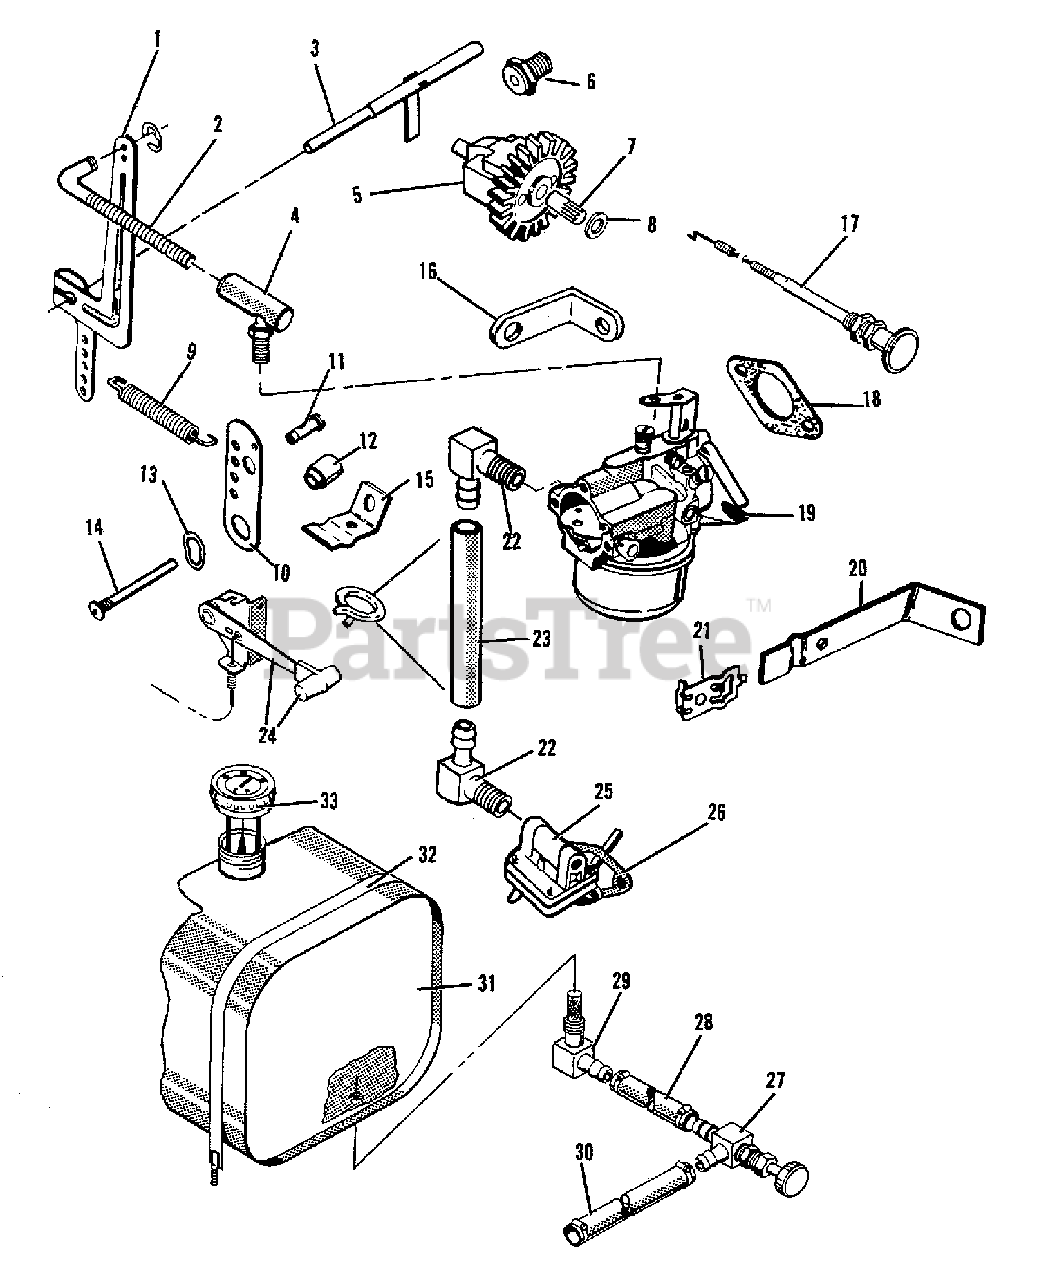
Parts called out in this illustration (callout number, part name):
1	LEVER, Governor
1	SCREW, 1/4 NC x 1-1/4
1	NUT, 1/4 NC
2	ROD, Throttle
2	RETAINER, Rod
3	SHAFT ASSEMBLY, Governor Cross
4	JOINT ASSEMBLY, Ball
4	LOCKWASHER, #10
4	NUT, #10 NF
5	GEAR ASSEMBLY, Governor
7	SHAFT, Governor
8	WASHER, Thrust
9	SPRING, Governor
10	BRACKET, Speed Control
11	PIN, Wire Swivel
11	SCREW, 1/4 NC x 1/4
11	LOCKWASHER, 1/4
13	WASHER, Tension
14	PIN, Governor Stop
15	BRACKET, Throttle
15	SCREW, #10 NC x 3/8
15	LOCKWASHER, #10 Inter Tooth
16	BRACKET, Adjustment Screw
17	CHOKE ASSEMBLY, Carburetor Air
18	GASKET, Carburetor (Included in Engine Gasket Set)
19	CARBURETOR ASSEMBLY (10 & 12 H.P.)
19	CARBURETOR ASSEMBLY, (14 H.P.)
19	REPAIR KIT, Carburetor
20	BRACKET, Choke
21	CLIP, Choke Cable
22	ELBOW, Hose
23	HOSE, Fuel (Pump to Carburetor)
23	CLAMP, Hose, 7/16 to 25/32
24	LEVER ASSEMBLY, Throttle Control
24	KNOB, Handle
25	PUMP ASSEMBLY, Fuel
26	GASKET, Fuel Pump (Included In Engine Gasket Set)
27	VALVE ASSEMBLY, Fuel Shutoff
28	CLAMP, Hose, 7/16 to 25/32
29	ELBOW, Fuel
30	HOSE, Fuel
30	CLAMP, Hose, 7/16 to 25/32
31	TANK ASSEMBLY, Fuel
32	STRAP ASSEMBLY, Fuel Tank
33	CAP ASSEMBLY, Fuel (Guage Included)
